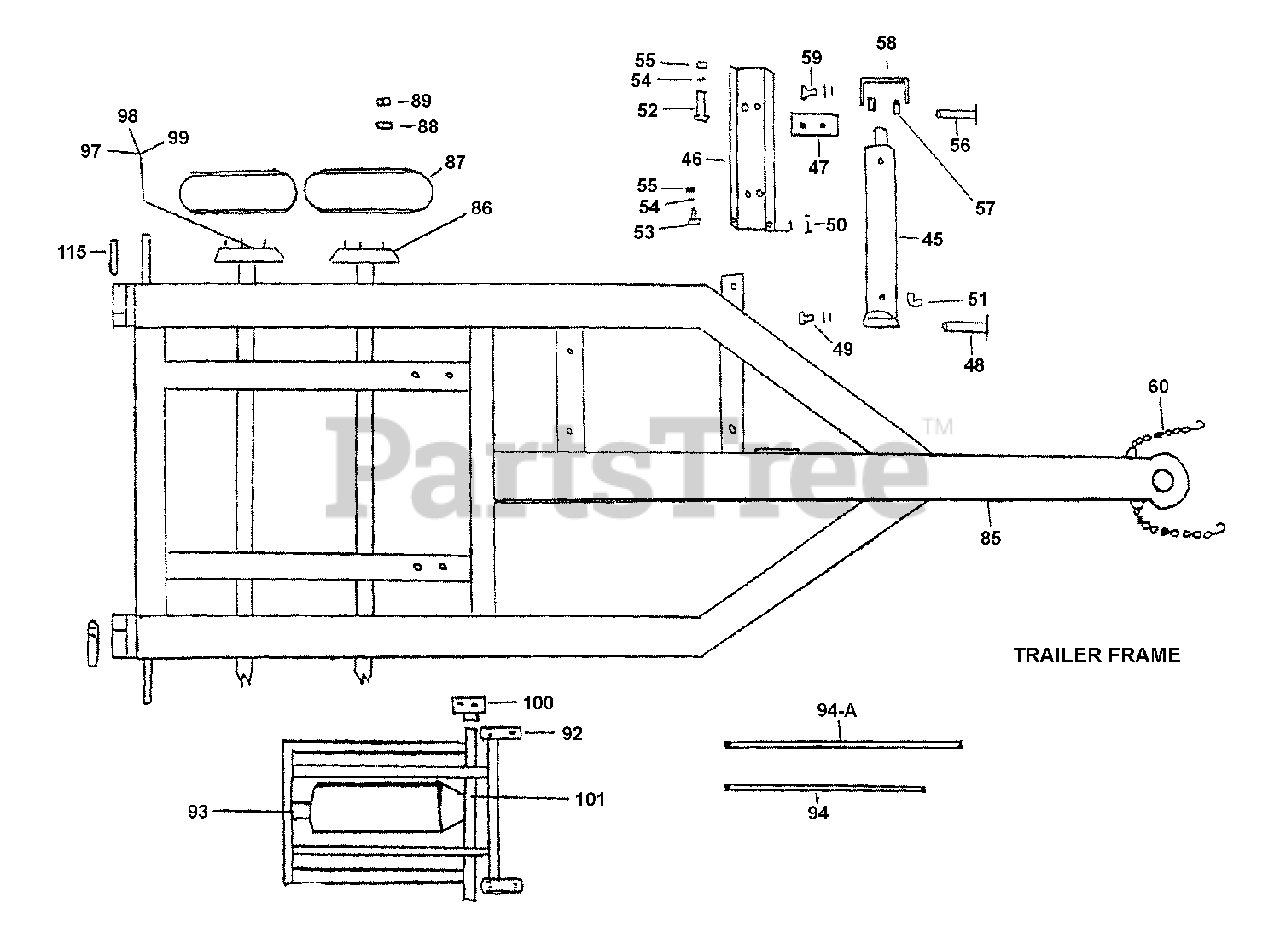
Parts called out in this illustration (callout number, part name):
45	Hydraulic Cylinder 24" (Hydraulic Jack Let)
46	Cylinder Mounting Bracket
47	Cylinder Clamp Bracket
48	Cylinder Top Mounting Pin 1-1/4 x 7
49	1/2-13 x 1-1/4 Bolt/Lock Washer/Flat Washer Group
50	3/8 x Clevis Pin & Bridge Pin
51	Hydraulic Fitting - 2501-6-8
52	1/2-13 x 5-1/2 Hex Bolt (Clamp Bolt)
53	5/8-11 x 1-1/2 Hex Bolt
54	5/8 Flat Washer (Modified 'D' Shape)
55	5/8-11 Hex Nut
56	Jack Foot Pin 1-1/4 x 5
57	1-1/4 ID x 3/4 Spacer
58	Jack Foot
59	1/2-13 x 1-1/4 Bolt/Lock Washer/Flat Washer Group
60	Safety Chain (Set of 2)
85	Trailer Frame (29 HP)
85	Trailer Frame (35 HP)
86	Axle and Spring Assembly
87	Tire & Rim Assembly 8-14.5LT
92	Hoist Box Brackets
93	Hoist Assembly - Complete
94	Hydraulic Hose - 1/2 x 123
94A	Hydraulic Hose - 1/2 x 143
98	Bearing Seal
99	Bearing
100	Hoist Trailer Bracket
101	Hoist Pin
115	Tail Light Assembly with Mounting Ring
